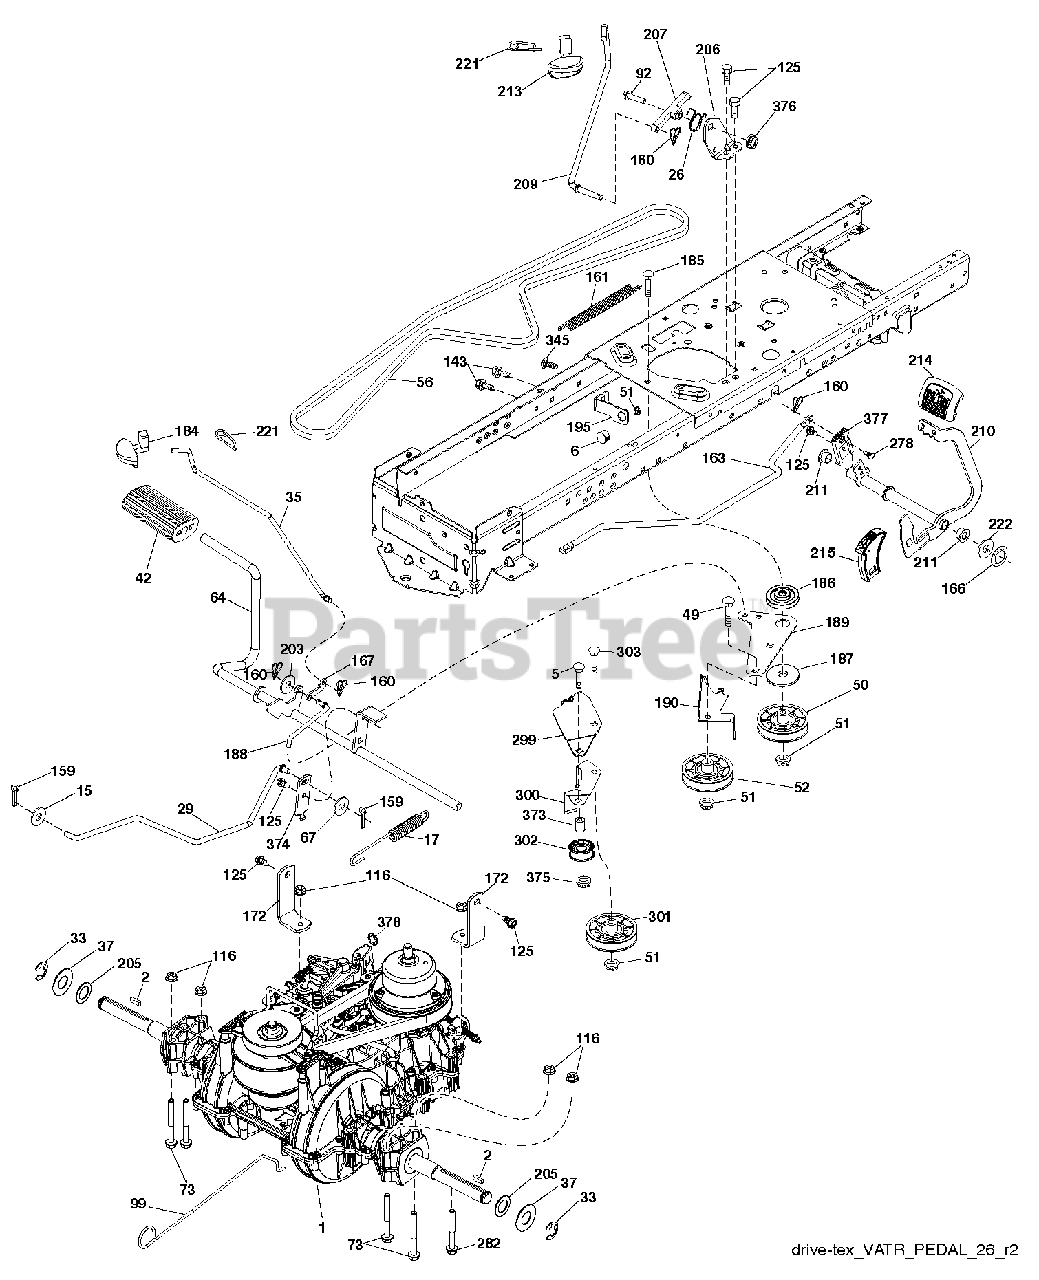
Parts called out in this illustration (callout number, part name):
2	SQUARE KEY
5	LOCKNUT
6	GROMMET T
17	Brake Variator Spring
26	SPRING.RETURN.CRUISE
29	RB ROD.BRAKE.VARIATOR.SD2
33	E-RING LT
35	ROD .BRAKE. PARKING. GT. HUSQ.
37	WASHER.HARDENED
49	BOLT
50	IDLER.FLAT.910.OFFSET
51	NUT LOCK FLG 3/8-16 UNC
52	IDLER.V-GROOVE.910.OFFSET
56	BELT.DRIVE.MOWER.TEX.42"
64	SUBASM.SHAFT.PEDAL.BRAKE
67	WASHER
73	BOLT HEX 5/16-18 GR 5
92	BOLT
99	ROD.BYPASS.VARIATOR.GEN2
116	NUT LOCK HEX FLANGE 5/16-18
125	SCREW
143	SCREW LT
159	COTTER PIN
160	RETAINER CLIP
161	SPRING, RETURN LT
163	ROD.CONTROL.PEDAL.VARIATOR
166	NUT.PUSH.625
167	LATCH.BRAKE.SPRING
172	STRAP.TORQUE.VARIATOR
184	HANDLE.PARKG.BRK.HUSQ/PRED.667
186	SPACER.RETAINER
187	WASHER 12/32X2X10GA
188	LINK.CLUTCH.GROUND.DRIVE
189	BELLCRANK.GROUND.DRIVE.TEX.
190	KEEPER.BELLCRANK.DRIVE
195	BRACKET.BRAKE.BRAKE.VAR.SD
203	WASHER
206	BRACKET.MOUNT.CRUISE.LATCH
207	LATCH.CONTROL.CRUISE.VARIATOR
209	Control Cruise Rod, GT
210	WELDMENT.PEDAL.VARIATOR
211	BEARING.NYLON
213	Control Crusie Knob, Hu
214	PEDAL.FORWARD.PAD.TEX
215	CAP.PEDAL.REVERSE.VARIATOR
221	RETAINER.SPRING.CLIP.H
222	WASHER 21/32 X 1-1/4 X 10 GA.
278	Cruise Variator Bolt
282	BOLT HEX FLGHD 5/16-18X3 GR. 5
299	BRACKET.MOUNT.IDLERS
300	KEEPER.IDLERS.REAR.VARIATOR
301	PULLEY.IDLER.V-GROOVE
302	PULLEY.IDLER.FLAT.2"
303	BOLT CARRIAGE
373	SPACER.IDLER
374	ARM.CONTROL.BRAKE
376	NUT.FLANGE.HEX.5/16X18.BLACK
377	GEAR.SECTOR.CONTROL.CRUISE.VAR
378	NUT.PUSH.8MM
